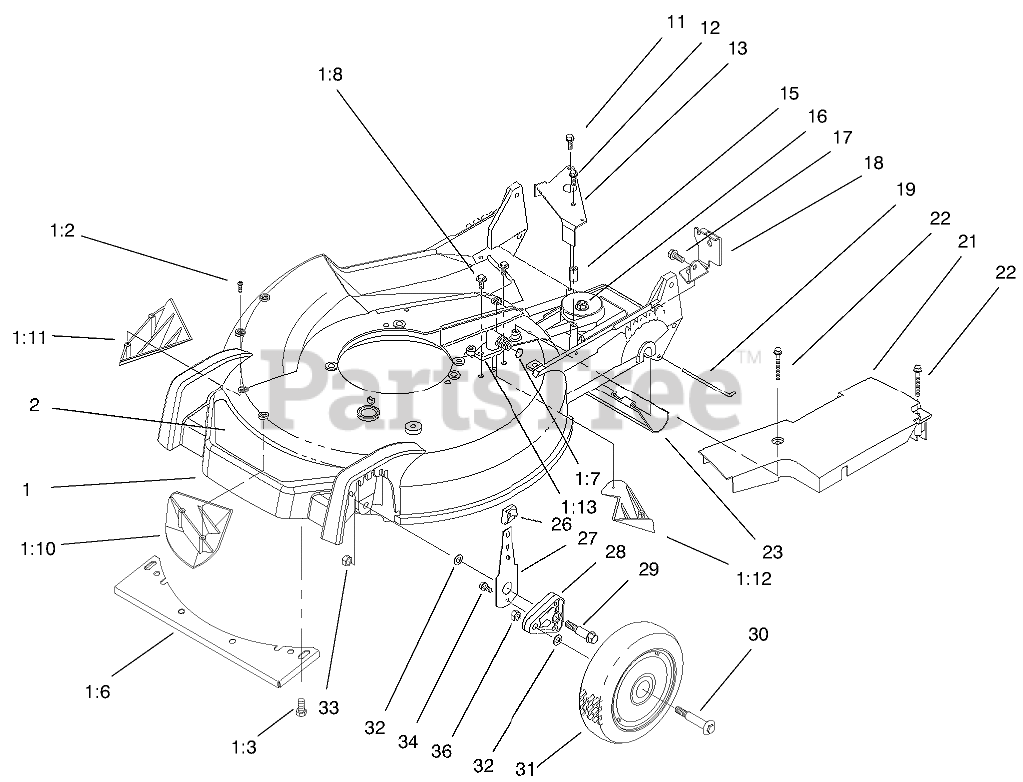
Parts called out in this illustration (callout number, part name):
1	HOUSING ASM
1:2	SCREW-PPH
1:3	SCREW-HWHTF
1:7	O-RING
1:8	SCREW-HWH
1:10	KICKER-FRONT
1:11	KICKER-RH
1:12	KICKER-REAR
1:13	FITTING-WASHOUT
2	DECAL-DECK
11	SCREW-HWHTF
12	SCREW-HWHTF
13	BRACKET-TRANSMISSION ACTUATOR
15	BUSHING-PLATE, ACTUATOR
16	ASM-Gearcase
17	SCREW-HWHTF
18	BRACKET-CABLE, TRACTION
19	ROD-SHIELD
21	COVER-BELT
22	SCREW-HHFTF
23	SHIELD-TRAILING
26	KNOB-ARM
27	FRONT SPRING ARM ASM
28	ARM-PIVOT, FRONT
29	BOLT-SHOULDER
30	BOLT-SHOULDER
31	WHEEL ASM
32	WASHER
33	NUT-LOCK
34	SCREW-HWH
